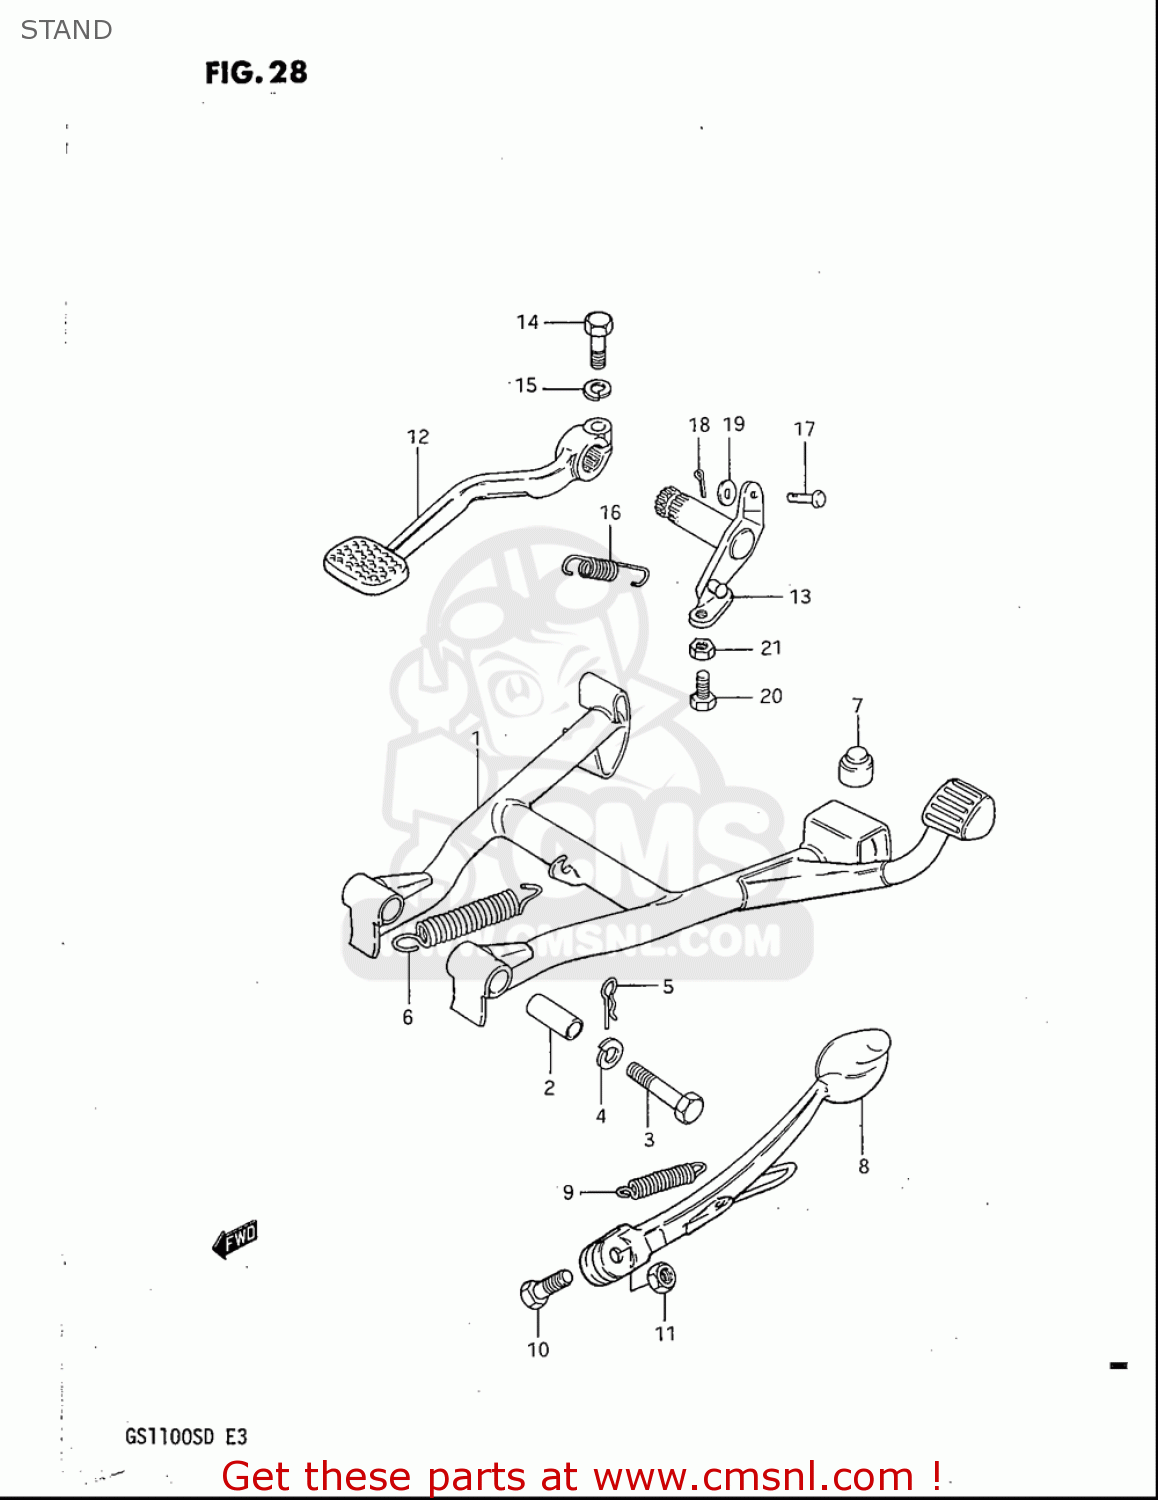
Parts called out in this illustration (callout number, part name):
1	STAND,CTR
2	SPACER(10X16X38.8)
3	BOLT(10X65)
4	WASHER,LOCK
5	CLIP
6	SPRING
7	CUSHION
8	STAND,PROP
9	SPRING
10	BOLT(10X30)
11	NUT
12	PEDAL,BRAKE
13	ARM,BRAKE PEDAL
14	BOLT
15	WASHER,LOCK
16	SPRING
17	PIN(6X18.2)
18	PIN
19	WASHER
20	BOLT
21	NUT
